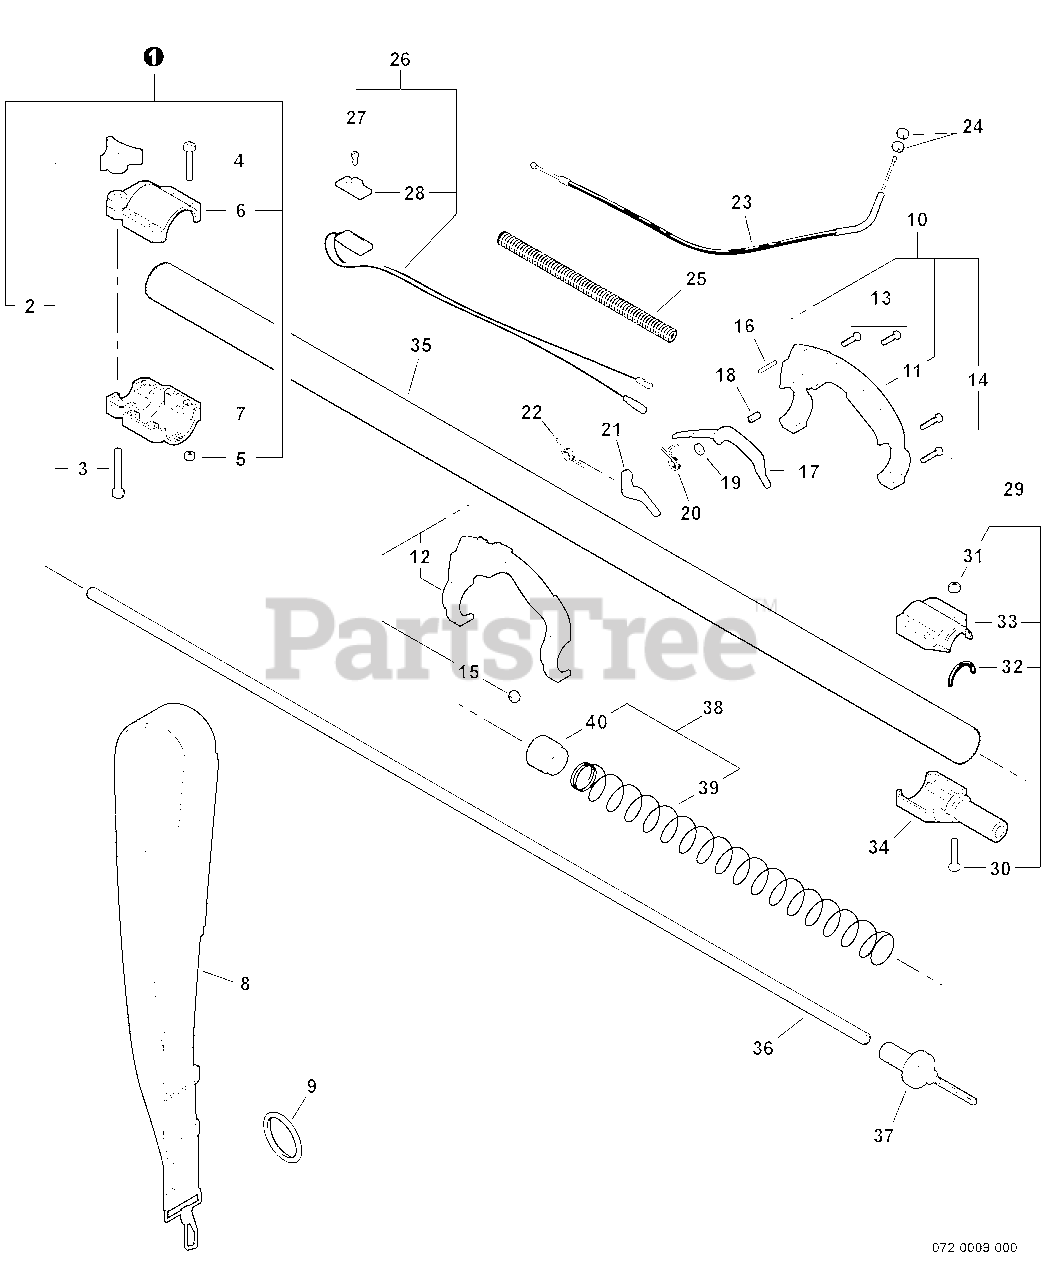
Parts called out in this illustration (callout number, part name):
1	COLLAR ASSY
2	THUMBSCREW
4	SCREW - 10-24 X 1-1/4"
5	LOCKNUT - 10-24
6	COLLAR, MAIN PIPE - UPPER
7	COLLAR, MAIN PIPE - LOWER
8	SHOULDER STRAP ASSY
10	HANDLE ASSY - REAR
11	HANDLE, REAR - LEFT
12	HANDLE, REAR - RIGHT
13	SCREW - 10-24 X 1-1/4"
15	LOCKNUT - 10-24
16	PIN - LOCATING
17	LOCKOUT, THROTTLE
18	COLLAR - 5
19	WASHER - 5
20	SPRING, LOCKOUT LEVER
21	TRIGGER, THROTTLE
22	SPRING, TRIGGER
23	CABLE, THROTTLE
25	TUBE, PROTECTIVE - CORRUGATED
26	IGNITION SWITCH ASSY
27	SCREW - 3X10
28	KNOB, SWITCH - ORANGE
29	MAIN PIPE CAP ASSY
31	LOCKNUT - 10-24
33	CAP, LOWER SHAFT TUBE ADAPTER
34	ADAPTER, LOWER SHAFT TUBE
35	PIPE, MAIN - ORANGE
36	DRIVESHAFT
37	SHAFT CONNECTOR
38	FLOATING BUSHING ASSY
40	BUSHING, FLOATING
